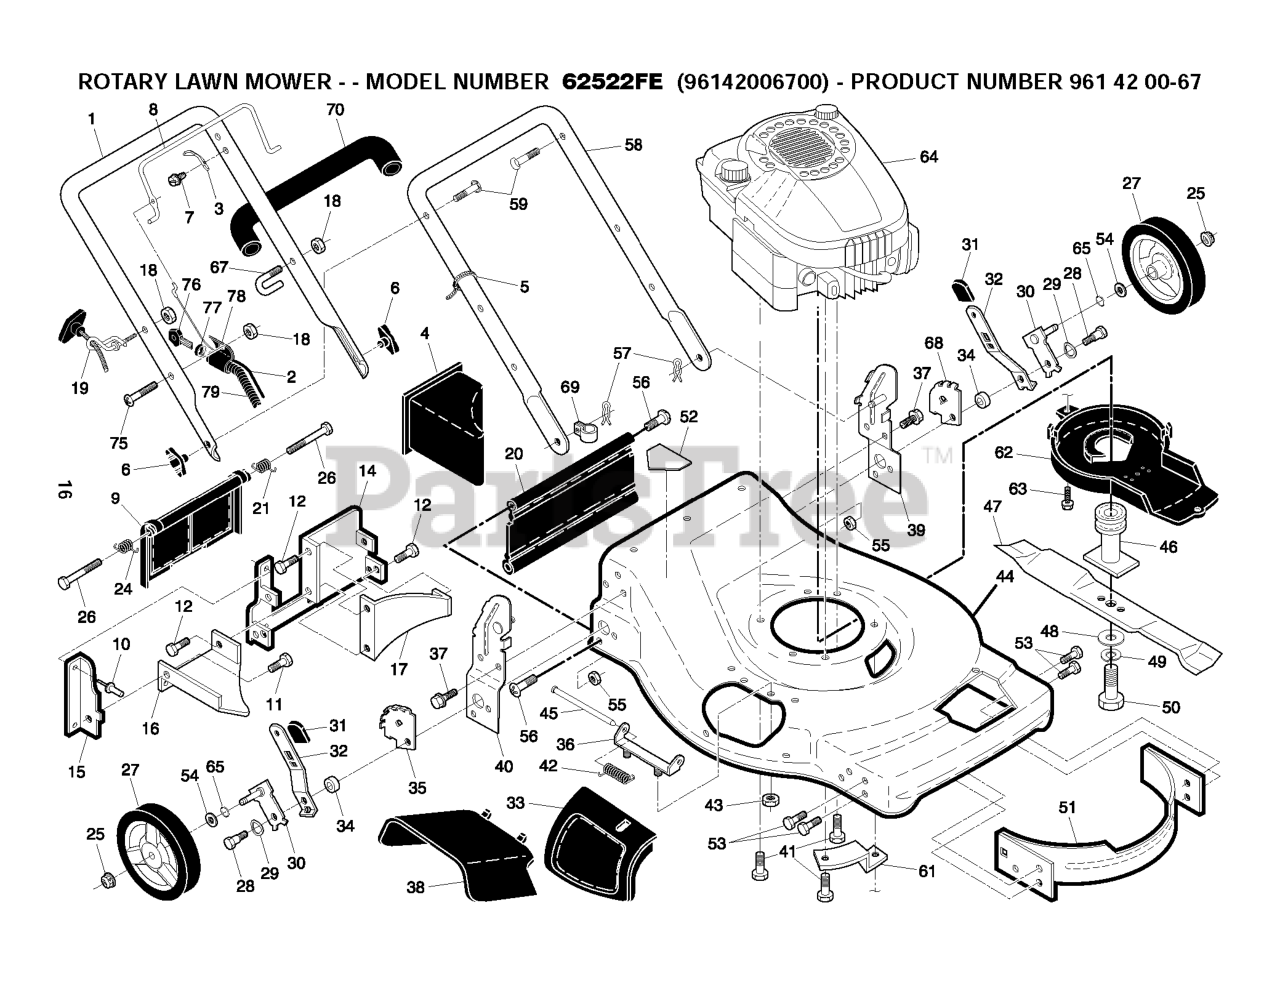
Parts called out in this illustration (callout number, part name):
1	HANDLE.ASM.UP.CREASED.GRAY
2	CABLE.MZR.W/KEY.START SW.51.62
3	BRACKET UPSTOP
4	PLUG.MULCH.22RD
5	TIE GUIDE
6	KNOB, DEFLECTOR
8	BAIL.MZR.CREA.ORANGE
9	REAR DOOR ASSY
10	RIVET BLIND
11	SCREW.HXTAP.10-24
12	SCREW 14-20 X 5/8
14	PLATE.BACK
15	SIDE BAFFLE
16	DISCHARGE BAFFLE
17	REAR BAFFLE
18	NUT
19	RB GUIDE.ROPE.STD.BLK.ZIN WSL
20	SKIRT.REAR.22RD/SD.FO/VE
21	SPRING.LH.22.REAR.DOOR.EZ.EMPT
24	SPRING.RH.22.REAR.DOOR.EZ.
25	NUT.HEX.FLANGE.3/8-16.LO(3 2)
27	WHEEL & TIRES ASSY, FRONT
28	BOLT SHOULDER 3/8 -16X1
29	WASHER.CURVED.CYLINDRICAL
30	AXLE ARM ASSY.
31	SELECTOR KNOB
32	SELECTOR SPRING, FRONT
33	DOOR.MULCH.22.REAR.FWGD.GREY
34	SPACER.HEIGHT.ADJUSTER
35	WHEEL ADJUSTING BRACKET
36	BRACKET.ASM.HINGE.21.FWGD.
37	SCREW
38	DEFLECTOR.CLIPPING.22.GREY
39	BRACKET.ASM.HDL.LT.EZEM.22.ORA
40	BRACKET.ASM.HDL.RT.EZEM.22.ORN
41	BOLT 3/8-16X1-1/8
42	SPRING.TORSION
43	LOCKNUT.NYLOC.1/4-20
44	HOUSING.22.TORUS.FWD.ORANGE.WA
45	ROD.HINGE.21
46	BLADE ADAPTOR / PULLEY
47	BLADE.22.MULCH.STANDARD
48	WASHER,HARDEN
49	LOCKWASHER
50	SCREW, HEX HD 3/8-24 X 1-3/8
51	FRONT BAFFLE KIT
52	DANGER DECAL
53	SCREW 1/4X20
54	WASHER.FLAT.1/2
55	LOCKNUT
56	HINGE SCREW
57	HAIRPIN COTTER
58	HANDLE.LOWER.PNT
59	BOLT, HANDLE 5/16-18X1.75
61	BRACKET
62	DEBRIS SHIELD
63	SCREW.HEX.WSH
65	O-RING..070X.487.NEOPRENE
67	CLIP.WIREFORM.PACK.TOR
68	WHEEL ADJUSTING BRACKET LH
69	CLIP.CABLE.BLK
70	GRIP, FOAM
75	SCREW.(COMBINATION CONTROL)
76	KEY.MOLDED
77	NUT.CAP.SNAP-ON.KEY START
78	KIT.CONTROL.COMBI.KEYW/HARNESS
79	HARNESS.WIRING.CONTROL
